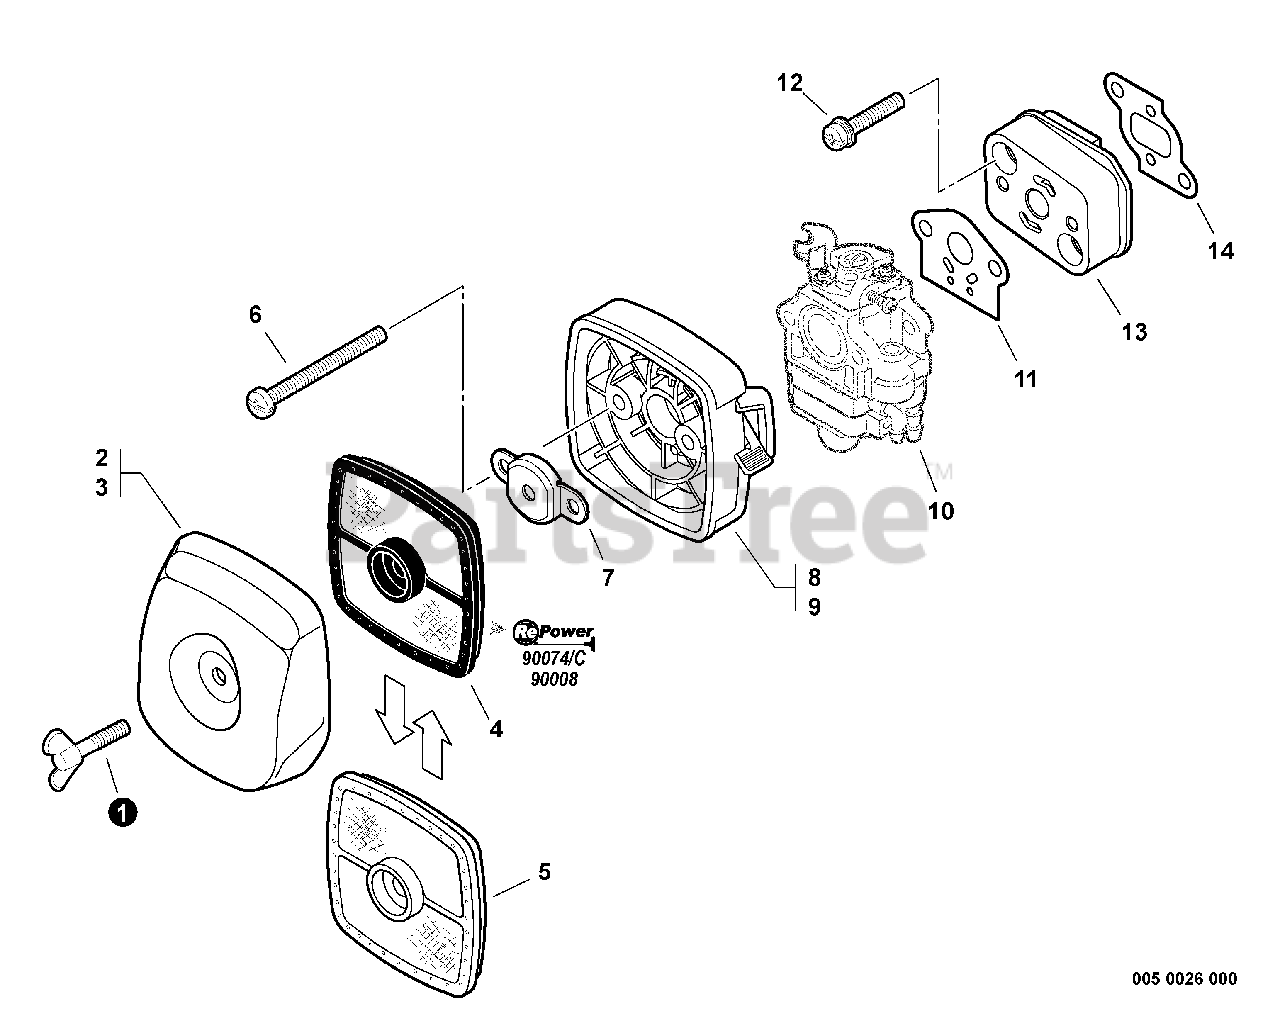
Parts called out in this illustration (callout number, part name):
1	BOLT, WING 5×20
2	COVER, AIR FILTER - GRAY
3	COVER, AIR FILTER - BLACK
4	FILTER, AIR - DOUBLE LAYER
5	FILTER, AIR - SINGLE LAYER
6	SCREW 5×60
7	PLATE, PREVENT
8	CASE, AIR FILTER - GRAY
9	CASE, AIR FILTER - BLACK
10	CARBURETOR
11	GASKET, CARBURETOR
12	BOLT 5×25
13	INSULATOR, INTAKE
14	GASKET, INTAKE
15	TUNE-UP KIT - REPOWER
16	FILTER KIT - REPOWER
